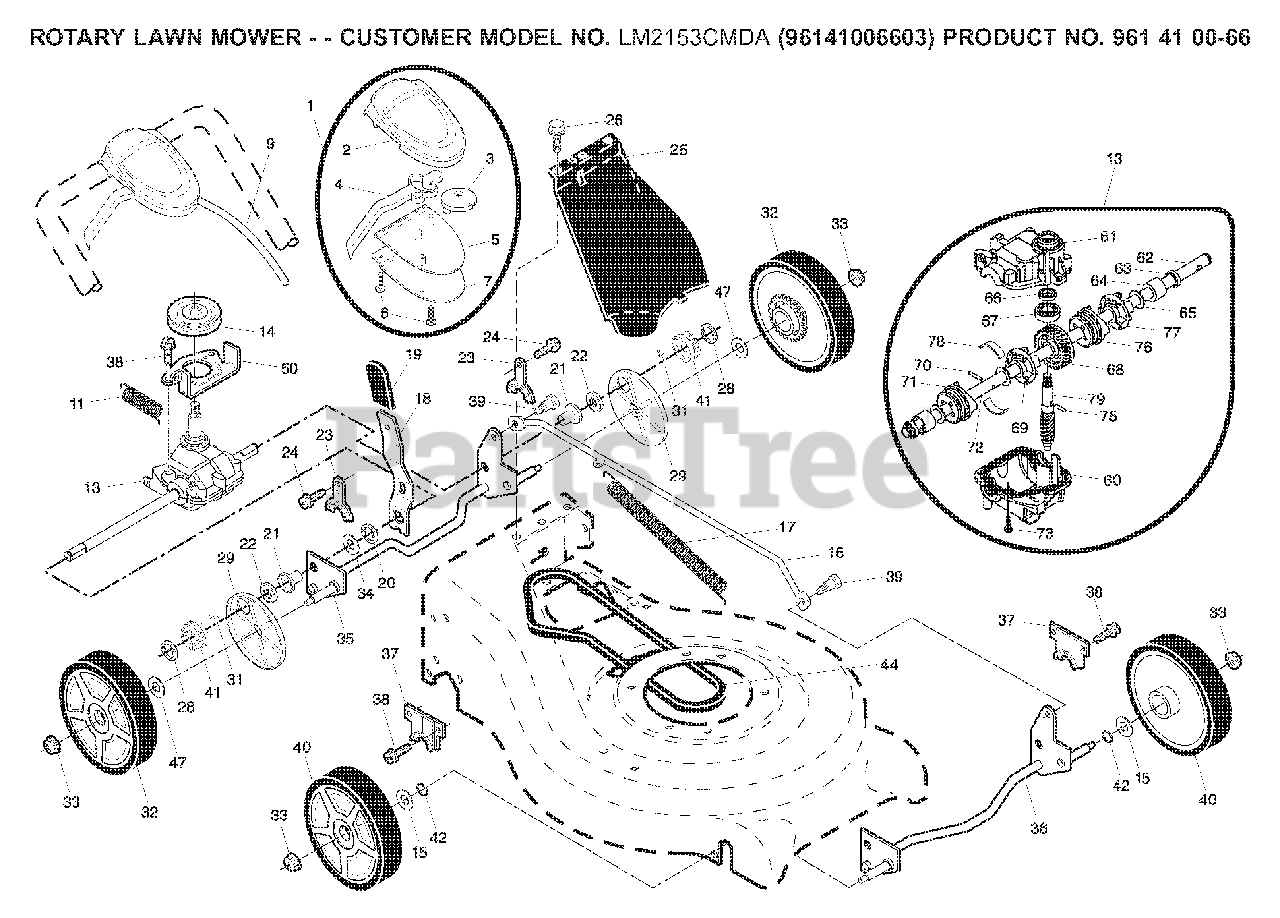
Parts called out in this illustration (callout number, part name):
2	COVER, TOP DRIVE CONTROL
3	PULLEY.CAM.DRIVE.CONTROL.EZ
5	COVER BOTTOM DRIVE CNTRL BLACK
6	SCREW, PHILLIPS HEAD 10 X 5/8
7	BRACKET.DRIVE.CONTROL.MOUNT
9	CABLE.ASSY.RGD.EZ.AUTO
13	TRANSMISSION.21.RWGD.AUTO.SP
14	PULLEY.1.PIECE
15	WASHER PM
16	ROD.CONNECTING.SPT.BLACK
17	SPRING EXTENSION
18	SPRING.SELECTOR.SPT.21
19	KNOB, SELECTOR SPRING
21	BEARING SUPPORT
22	BEARING
23	BRACKET
28	E-RING 7/16 RE
29	COVER.DUST.WHEEL
31	PAWL, DRIVE
32	WHEEL.8X1.75.
33	NUT.HEX.FLANGE.3/8-16.LOCKNUT
35	SHAFT ASSY REAR
36	SHAFT ASSY, FRONT
37	RETAINER.FRONT.SHAFT
39	SHOULDER BOLT SEMI GIMLET PT.
40	FRONT WHEEL AND TIRE ASSY 8X2
41	PINIION.14.TOOTH.RGD
42	O-RING..070X.487.NEOPRENE
44	BELT.RGD.VS
47	WASHER FLUT
50	BELT KEEPER
60	CASE, LOWER
61	CASE UPPER
62	SHAFT OUTPUT LONG
63	SEAL.OUTPUT.SHAFT
66	SEAL INPUT SHAFT
68	GEAR 28 TEETH
69	FIXED DOG CLUTCH LH
70	PIN 7 33732
71	MOVEABLE DOG CLUTCH LH
72	SHAFT OUTPUT SHORT
75	PIN 3.50.337
76	FIXED DOG CLUTCH RH
77	MOVEABLE DOG CLUTCH RH
78	SPRING LEAF
79	SHAFT WORM
